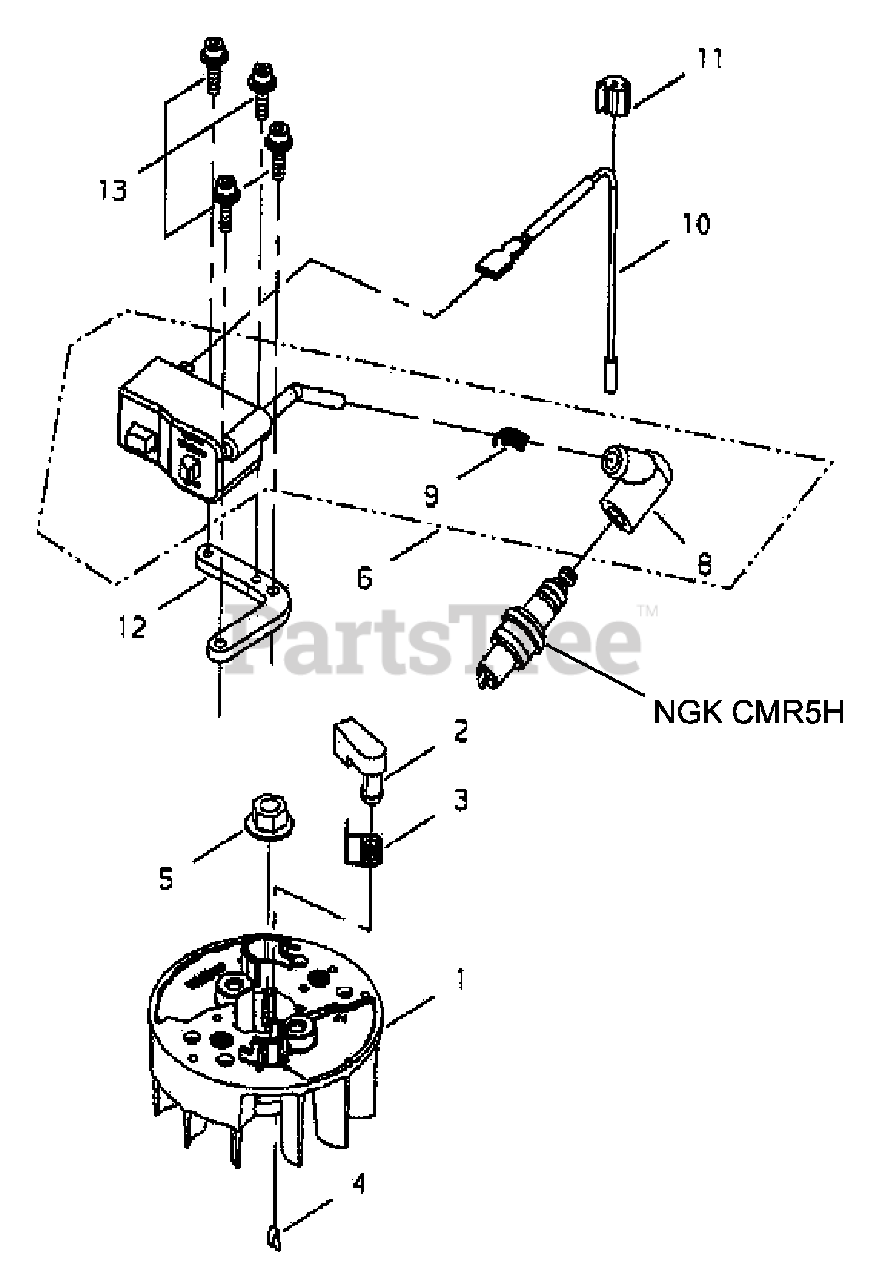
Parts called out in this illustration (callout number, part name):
1	FLYWHEEL
2	PAWL
3	SPRING, TORSION
4	KEY, WOODRUFF 3×10
5	NUT M8
6	IGNITION COIL ASSY
8	CAP, SPARK PLUG
9	TERMINAL, SPARK PLUG
10	LEAD - IGNITION
11	GROMMET, LEAD
12	BRACKET
13	BOLT M4×16
